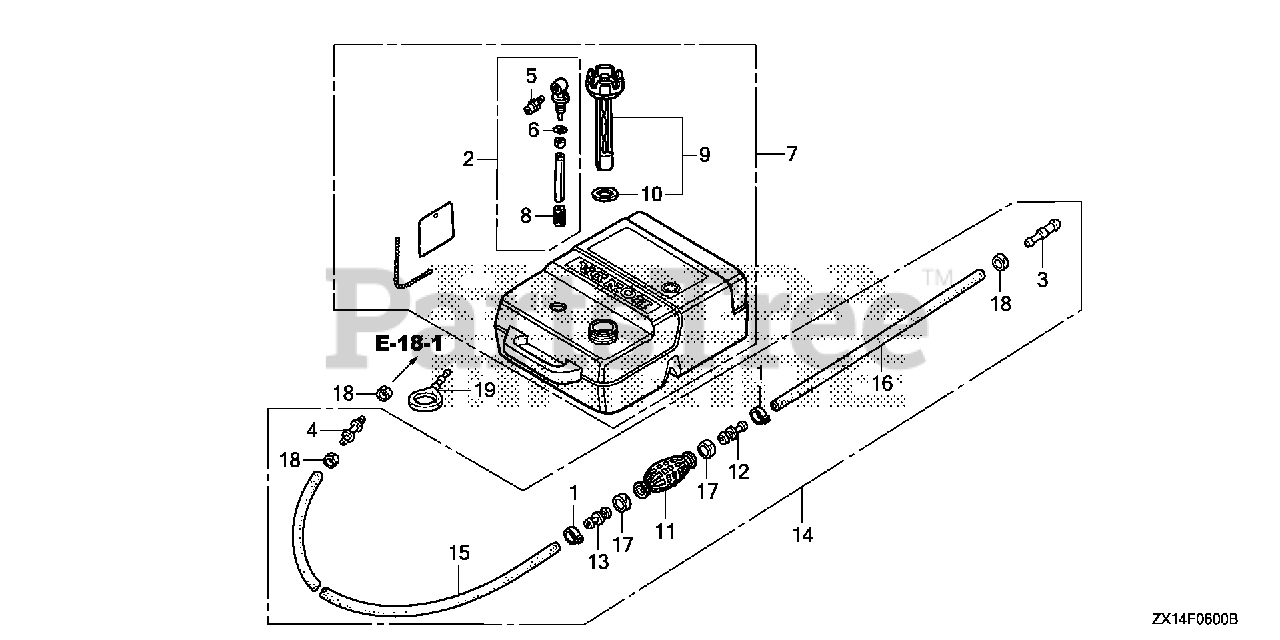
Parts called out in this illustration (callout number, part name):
1	CLAMP, FUEL TUBE
2	JOINT ASSY., FUEL
3	JOINT, FUEL TUBE
4	JOINT, FUEL TUBE
5	FITTING, QUICK DISCONNECT
6	O-RING
7	TANK ASSY., FUEL
8	FILTER, FUEL
9	CAP, FUEL FILLER
10	GASKET, FUEL CAP
11	BULB, PRIMER
12	VALVE, IN.
13	VALVE, OUTLET
14	TUBE ASSY., FUEL TANK (JOINT TYPE)(FKM)
15	TUBE, FUEL LONG (7.3X2000)
16	TUBE, FUEL SHORT (7.3X500)
17	BAND, TUBE CLIP (20MM)
18	BAND, TUBE CLIP (12.5MM)
19	PLUG, FUEL TUBE
